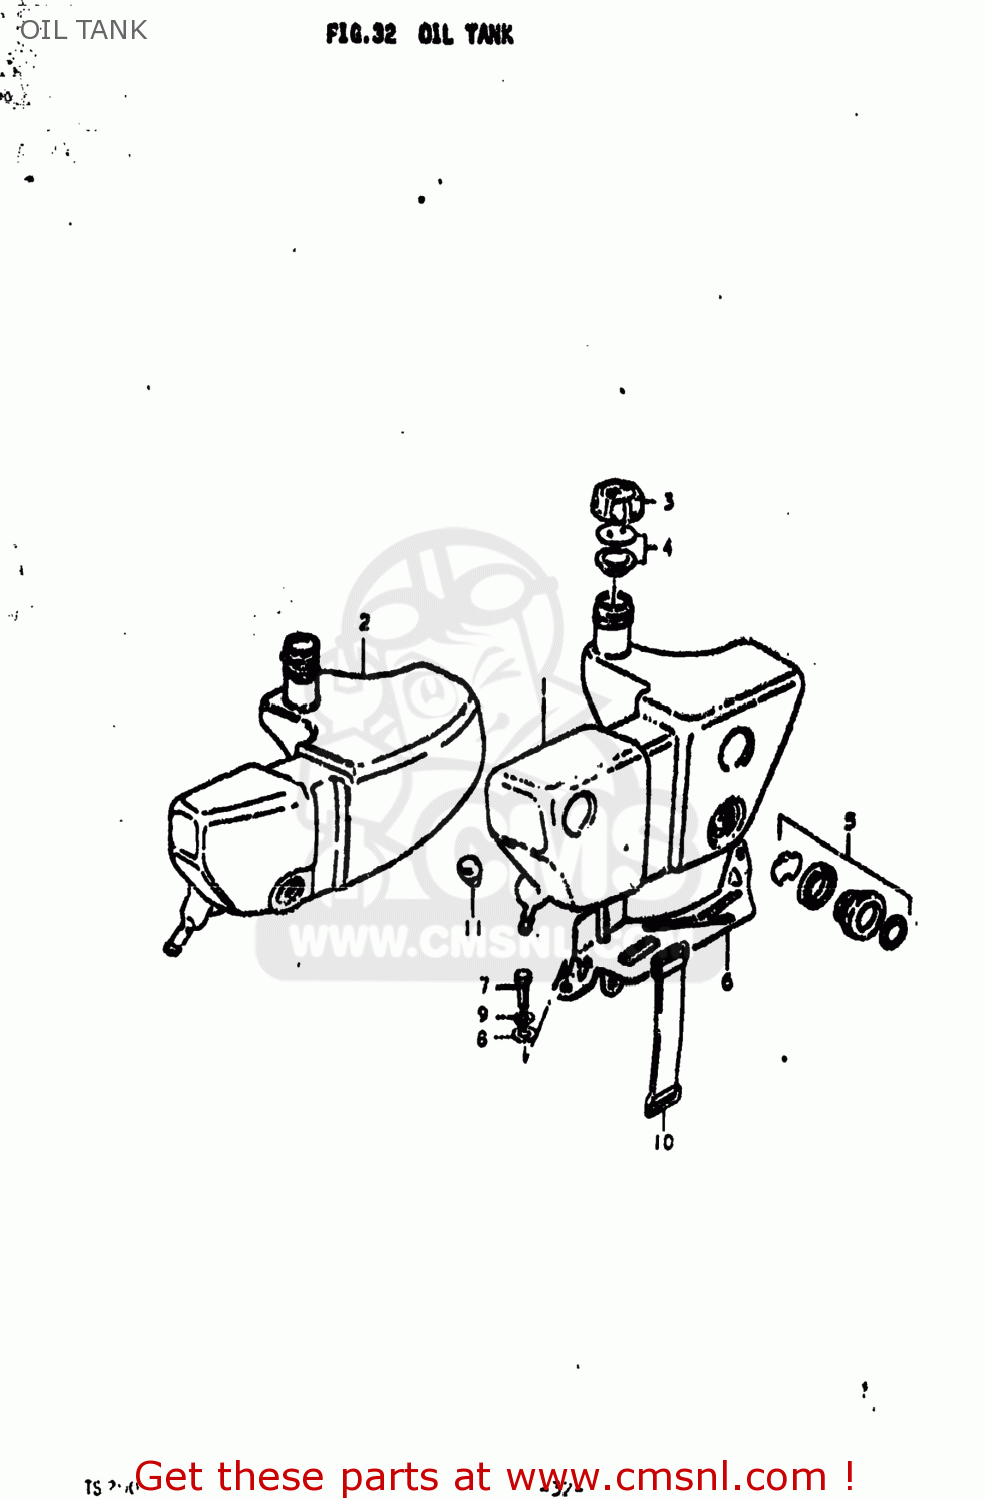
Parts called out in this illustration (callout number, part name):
1	TANK,OIL
2	TANK,OIL
3	CAP,OIL TANK
4	LENS,OIL LEVEL INSPECTION
5	LENS,OIL LEVEL INSPECTION
7	BOLT
8	WASHER
9	LOCK WASHER
10	BAND
11	CUSHION
